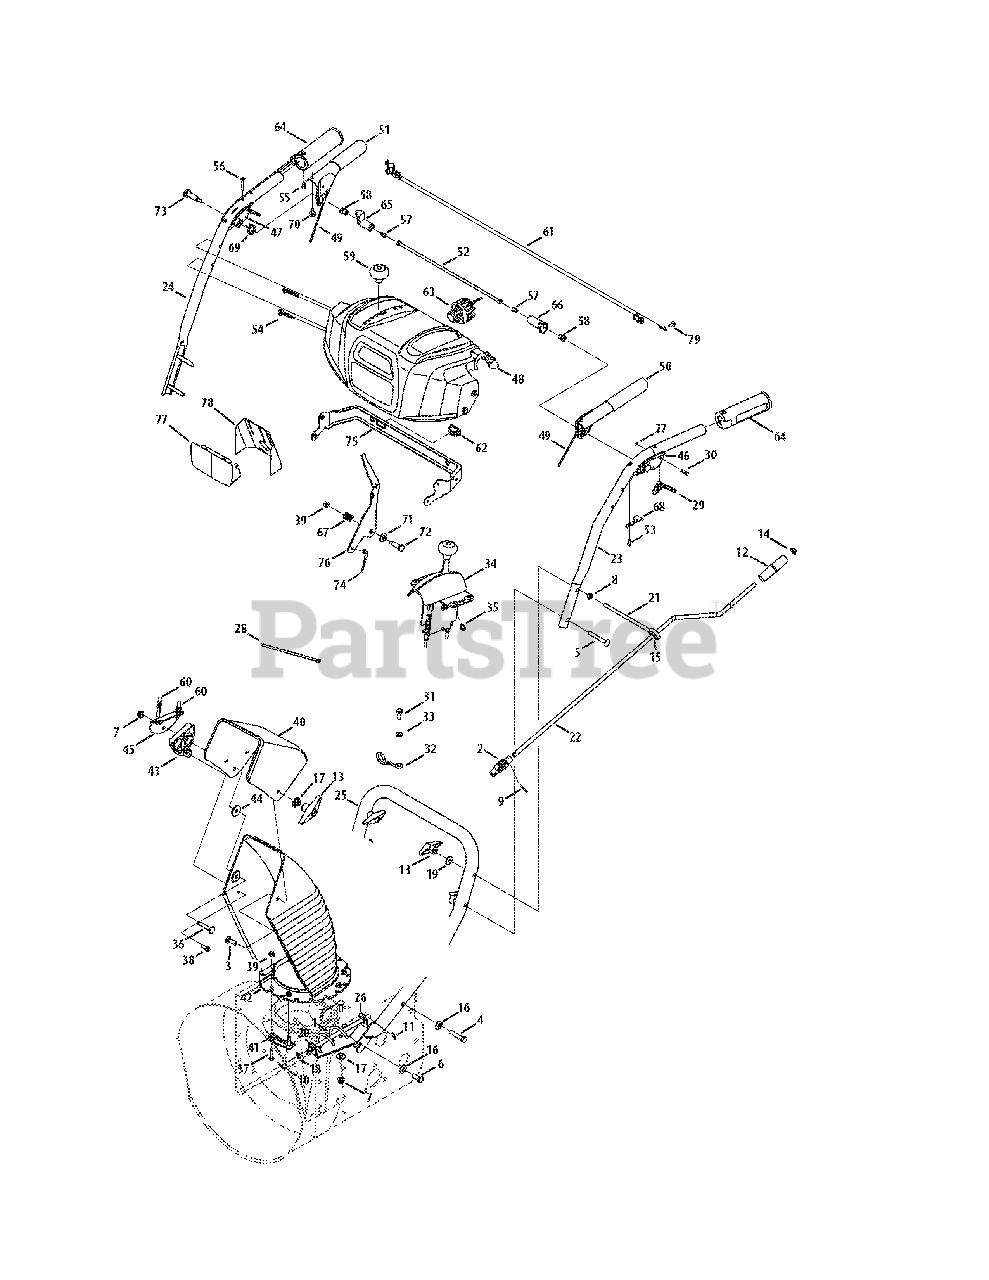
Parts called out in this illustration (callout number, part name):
1	Chute Crank Assembly
2	Joint Block Assembly
3	Screw, Carriage, 5/16-18 x 1.0
4	Screw, Hex, 3/8-16 x 2.00 Lock, Gr5
5	Screw, Carriage, 5/16-18 x 2.5
6	Screw, Hex, 3/8-16 x 1.0 Lock, Gr5
7	Flange Lock Nut, 5/16-18
8	Hex Nut, 5/16-18
9	Internal Cotter Pin
10	Internal Cotter Pin
11	Spring Pin
12	Knob, Crank
13	Knob, Wing Nut, 5/16-18
14	Cap, Push, 3/8
15	Grommet, Rubber
16	Washer, Bel, .375 x .87 x .063
17	Washer, Flat, .349 x .879 .063
18	Washer, .375 x .738 x .063
19	Washer, Belleville, .34 x .872 x .06
20	Plastic Bushing, .380 I.D.
21	Eye Bolt
23	Handle, Upper - LH
24	Handle, Upper - RH
25	Handle, Lower
26	Chute Crank Bracket
27	Ring, Retainer
28	Cable Tie
29	Trigger
30	Pin, 3/16
31	Hex Head Screw, MB 1.25
32	Cable Guide
33	Flat Washer, .330 x .630 x .0635
34	2-Way Chute Control™ Assy
35	Hi-Lo Screw, 1/4-15 x 0.5
36	Bolt, Carriage, 5/16-18 x 1.75
37	Screw, 1/4-20 x 1.00
38	Hi-Lo Screw, 1/4-15 x .75
39	Flange Lock Nut, 1/4-20
40	Upper Chute
41	Chute, Flange Keeper
42	Lower Chute
43	Chute Tilt Cable Guide
44	Flat Washer
45	Cable Bracket
46	Handle Clutch Lock - LH
47	Handle Clutch Lock - RH
48	Handle Panel
49	Cable Assembly, Auger/Drive
49	Cable, Clutch
49	Spring, Extension
50	Handle Engage Assy - LH
51	Handle Engage Assy - RH
52	Rod Ass’y, Clutch Lock Pivot
53	Screw, #8-16 x 0.50
54	Screw, 1/4-20 x 1.625
55	AB Screw, #10-16
56	Screw, #10-24 x 0.375
57	Screw, 1/4-20 x.375
58	Shoulder Nut, 1/4-20
59	Shift Knob
60	Cable, Chute Tilt
61	Wiring Harness
62	Htd. Hand Grip on/off Switch
63	Light Socket
64	Heated Hand Grip
65	Lock Plate
66	Clutch Lock Cam
67	Compression Spring
68	Clutch Lock Spring
69	Torsion Spring
70	Rubber Bumper
71	Flat Washer, .385 x .87 x .06
72	Shoulder Screw
73	Shoulder Screw, 1/4-20 x 1.345
74	Speed Selector Cable
75	Panel Bracket
76	Shift Lever
77	Lens Panel
78	Reflector Label
79	Hex Screw, 1/4-20 x .50
